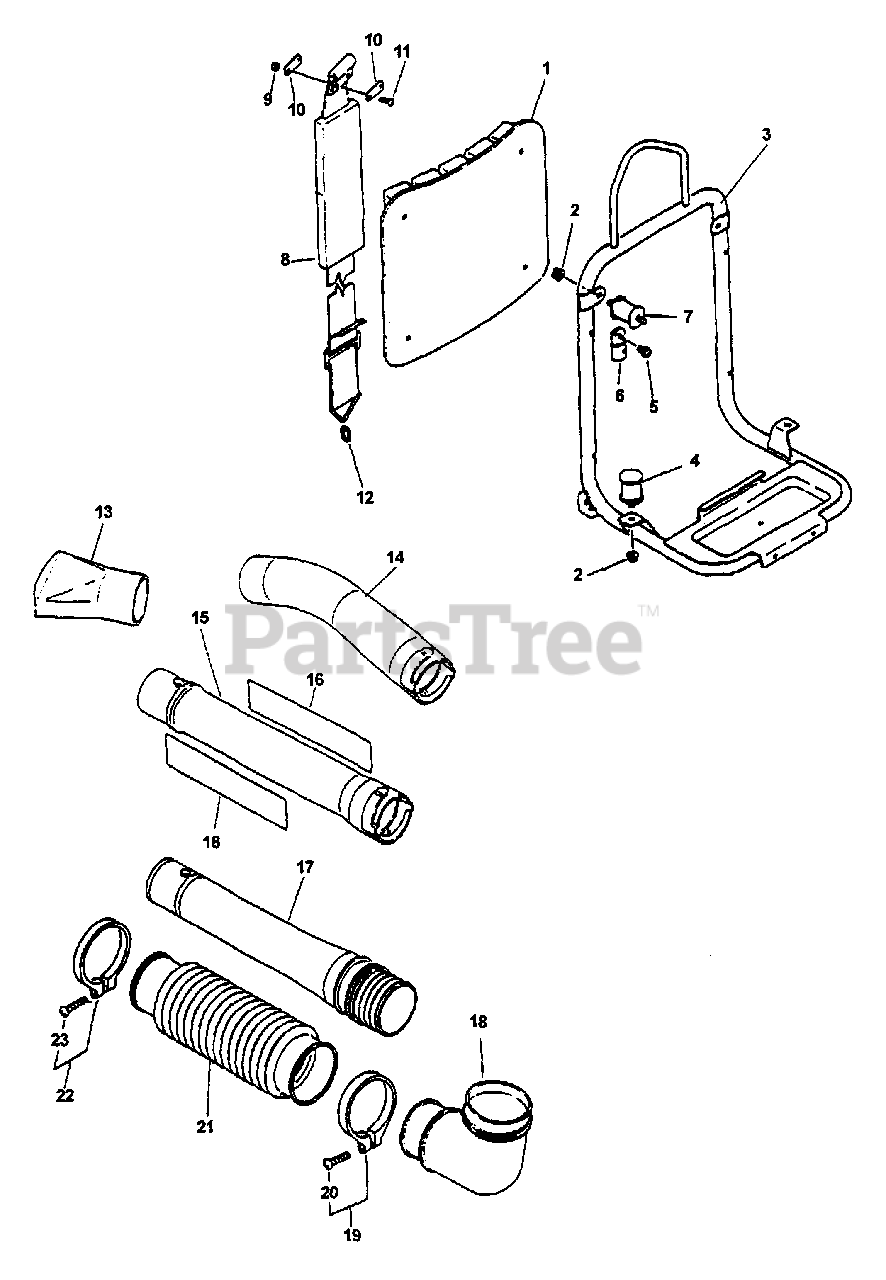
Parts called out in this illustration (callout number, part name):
1	CUSHION, BACKPACK
2	NUT, FLANGE M6
3	FRAME, BACKPACK
5	SCREW 5×10
6	BRACKET, CUSHION
8	HARNESS ASSY, BACKPACK
9	NUT, LOCK M5
11	SCREW 5×10
12	RING, HARNESS
13	NOZZLE - FAN HEAD
14	TUBE, BLOWER - CURVED
15	BLOWER TUBE KIT - STRAIGHT
16	LABEL - ECHO
17	TUBE, BLOWER - SWIVEL
19	CLAMP KIT
20	SCREW 5×30
21	TUBE, FLEXIBLE
22	CLAMP KIT
23	SCREW 5×30
